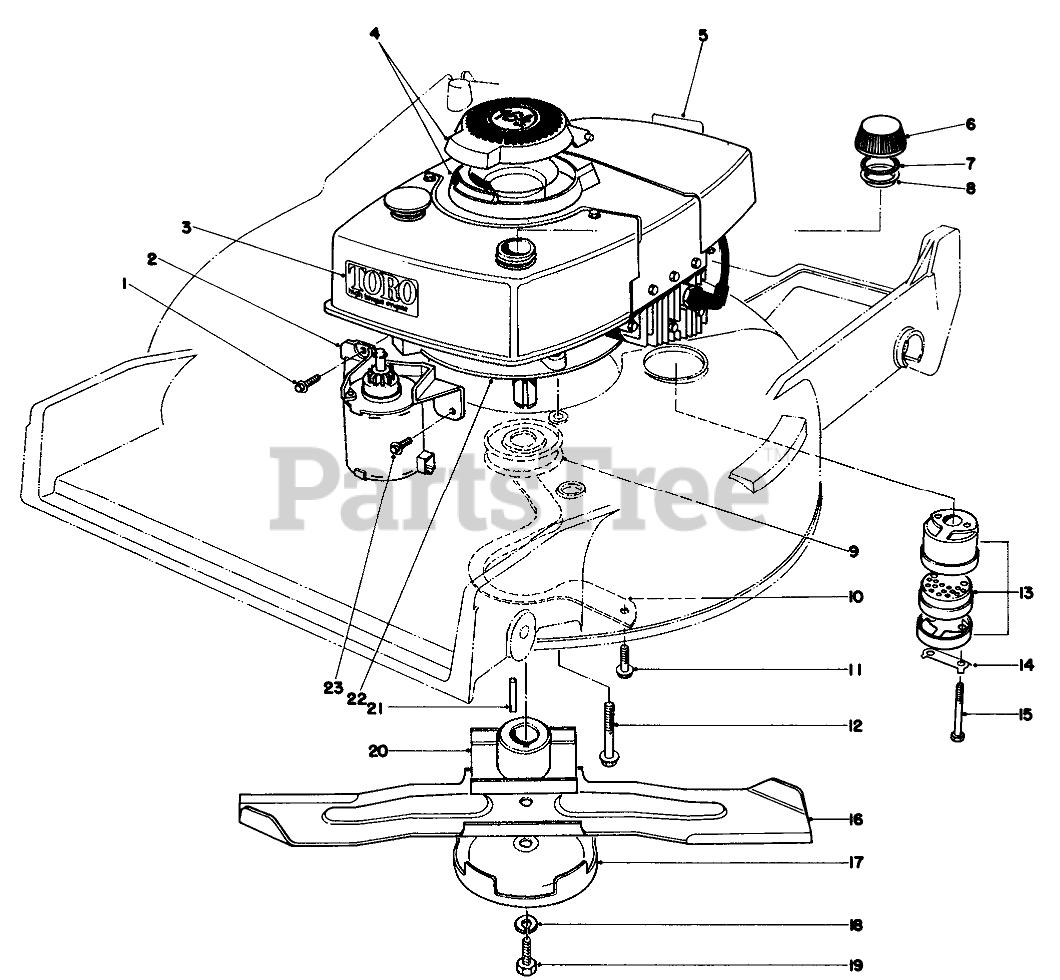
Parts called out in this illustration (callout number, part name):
1	Screw
2	Starter Motor
3	Decal-Toro High Torque
4	COVER ASM
5	Decal-Maintenance (French & Dutch)
6	Gas Cap (Incl. Ref. #7 & 8)
7	GASKET
8	GAS CAP BAFFLE
9	DRIVER PULLEY
10	BELT GUIDE
11	Screw
12	SCREW-HWHTF
13	Muffler Assy. (Incl. Ref. #14 & 15)
14	CLIP - LOCKING
15	SCREW-HH
16	Blade
17	AntiScalp Cup
18	WASHER-LOCK
19	BLADE SCREW
20	BLADE RETAINER WA(BLACK)
21	KEY-SQUARE
22	Engine
23	SCREW
